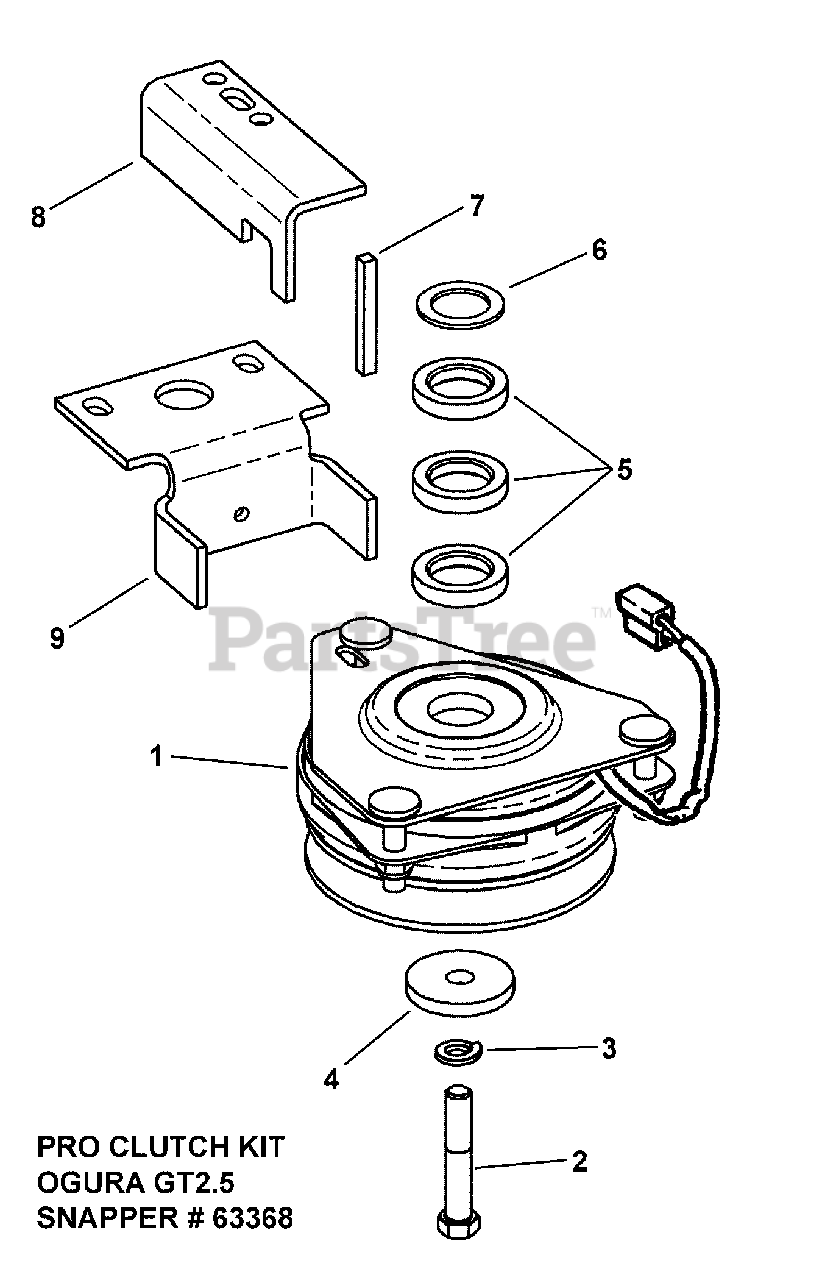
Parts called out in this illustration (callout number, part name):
1	CLUTCH, Electric Ogura GT2.5
2	SCREW, 7/16-20 x 2-1/2" Hex Head Cap (Special), GR 5
3	WASHER, 7/16" Split Lock
4	WASHER, .468 x 1.85 x .25 Flat
5	SPACER, Ogura Clutch
6	MACHINE BUSHING, 14 Ga.
7	KEY, 1/4" Square x 2-1/4"
8	BRACKET, Anti-Spin
9	BRACKET, Anti-Spin
